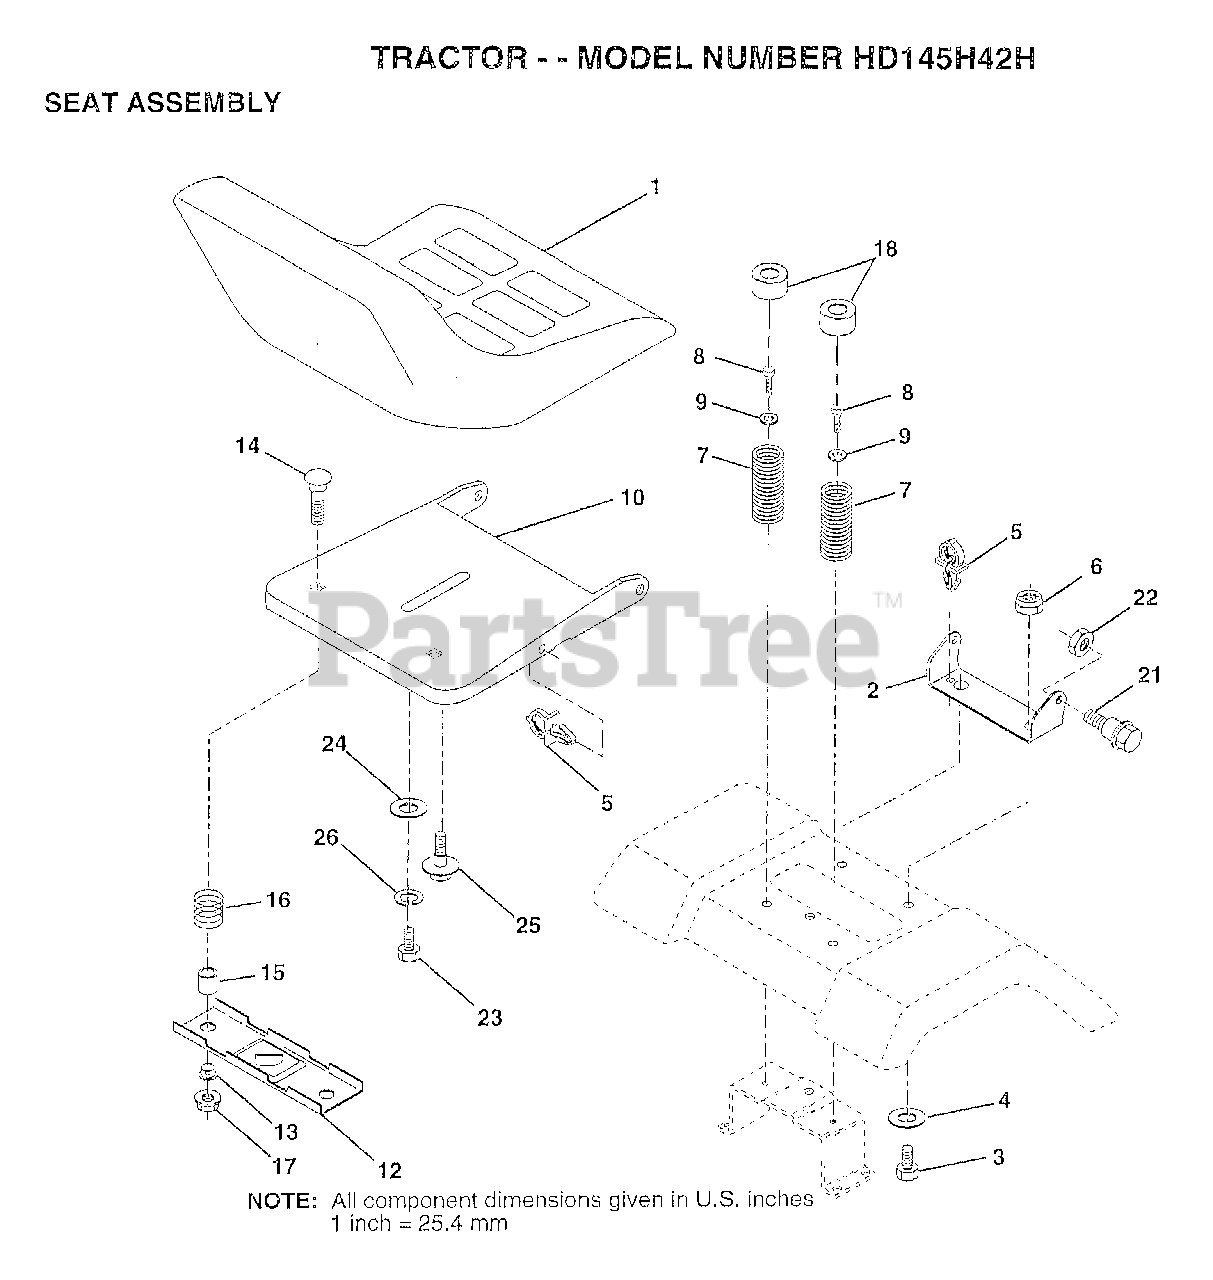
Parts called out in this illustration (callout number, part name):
1	SEAT
2	BRACKET PVT SEAT
3	BOLT
4	WASHER PM
5	CLIP.PUSH-IN.HING
6	NUT
7	SPRING COMPRESSIO
8	SCREW GTV
9	WASHER
10	PAN-SEAT
12	BRKT SWITCH
13	BUSHING
14	BOLT-RD HD SQ NK
15	SPLIT SPACER
16	SPRING
18	CAP SPRING
21	"BOLT,SHOULDER"
23	BOLT
24	WASHER
25	"BOLT,SHOULDER"
26	LOCKWASHER
